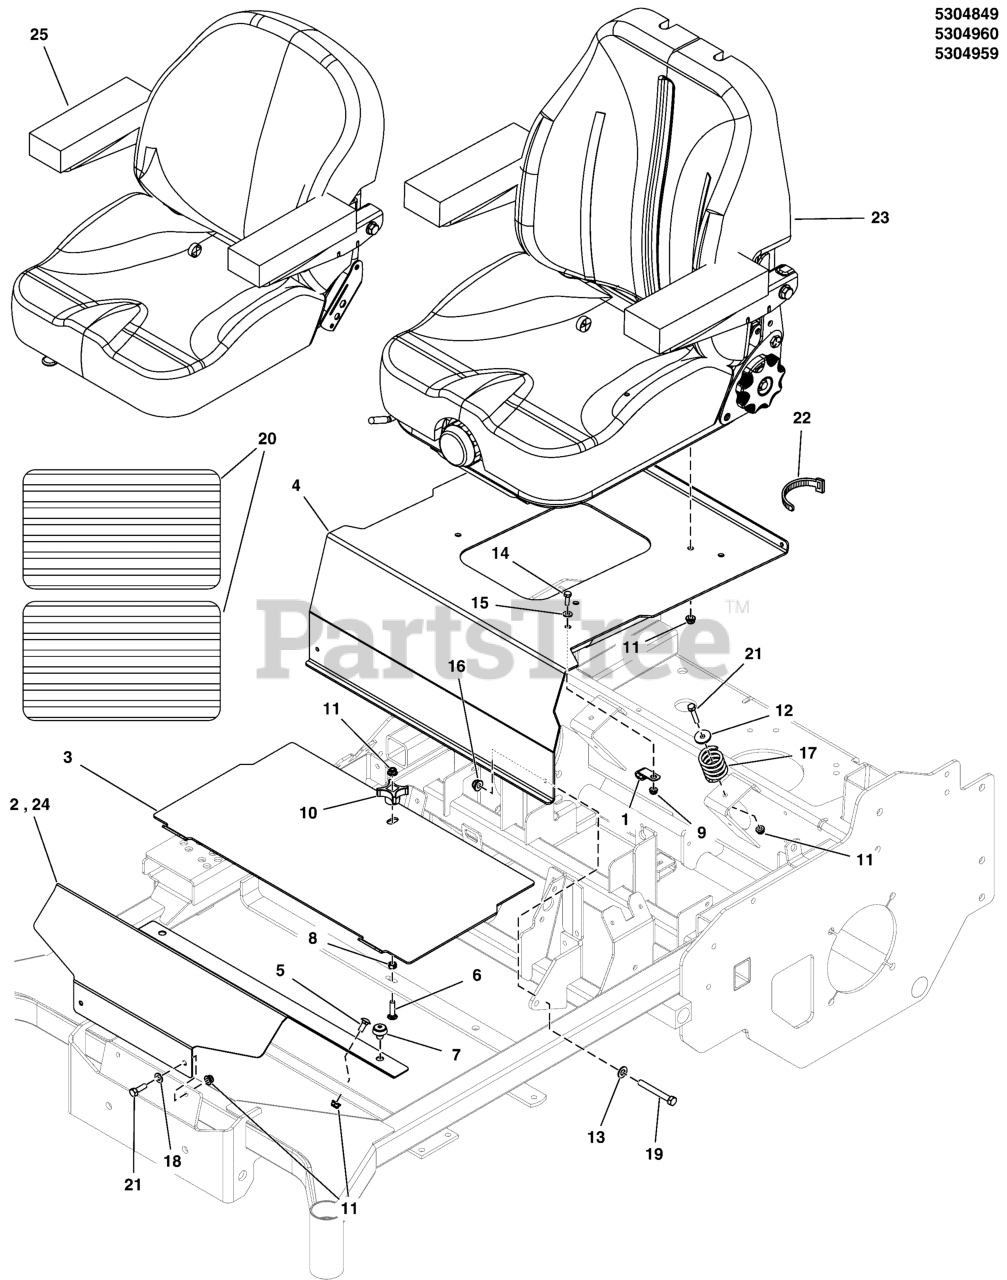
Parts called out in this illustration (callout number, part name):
1	CLAMP, 5/16", DOUBLE, WIRE & TUBE
2	PLATE, RIGID FLOOR, S320Z - RED
3	PLATE, REMOVABLE FLOOR, 200XT - RED
4	ASSM, SEAT PLATE W/DECAL - DOM (5415991D)
5	BOLT, 5/16-18 X 3/4, CARRIAGE, GD5, CZ
6	BOLT,5/16-18X1.500,CARRIAGE,SQ,GR5,ZC/CL
7	MNT, VBRTN, RBBR
8	NUT, 5/16-1/8, HEX, CNTR LK, ZINC PHOS/OIL
9	NUT, 1/4-20 Hex Nylock Flange
10	KNOB-INT THR .312-18 4-ARM 2.12WD 1.06LG
11	NUT, 5/16-18 HEX NYLOCK FLANGE NUT
12	WASHER, .34 X 1.25 X 10 GA
13	WASHER, 3/8 SAE
14	BOLT, 1/4"-20 X 3/4" GD5 YZ
15	WASHER, 1/4 SAE
16	NUT, 3/8 - 16 HEX NYLOCK FLANGE
17	SPRING, SEAT SUPPORT
18	WASHER, 5/16" SAE
19	BOLT, 3/8-16 X 3" GD5 CZ
20	SAFETY WALK, 10.00 X 19.00
21	BOLT, 5/16-18 X 1" GRD5 YZ
22	TIE, SELF-LOCKING, 6"
23	SEAT, HIGH BACK,SEAT'SINC,SUSP, W/SWITCH
24	PLATE, RIGID FLOOR, 200XT - RED
25	SEAT, C13, SEAT'SINC, 2016, W/SWITCH
